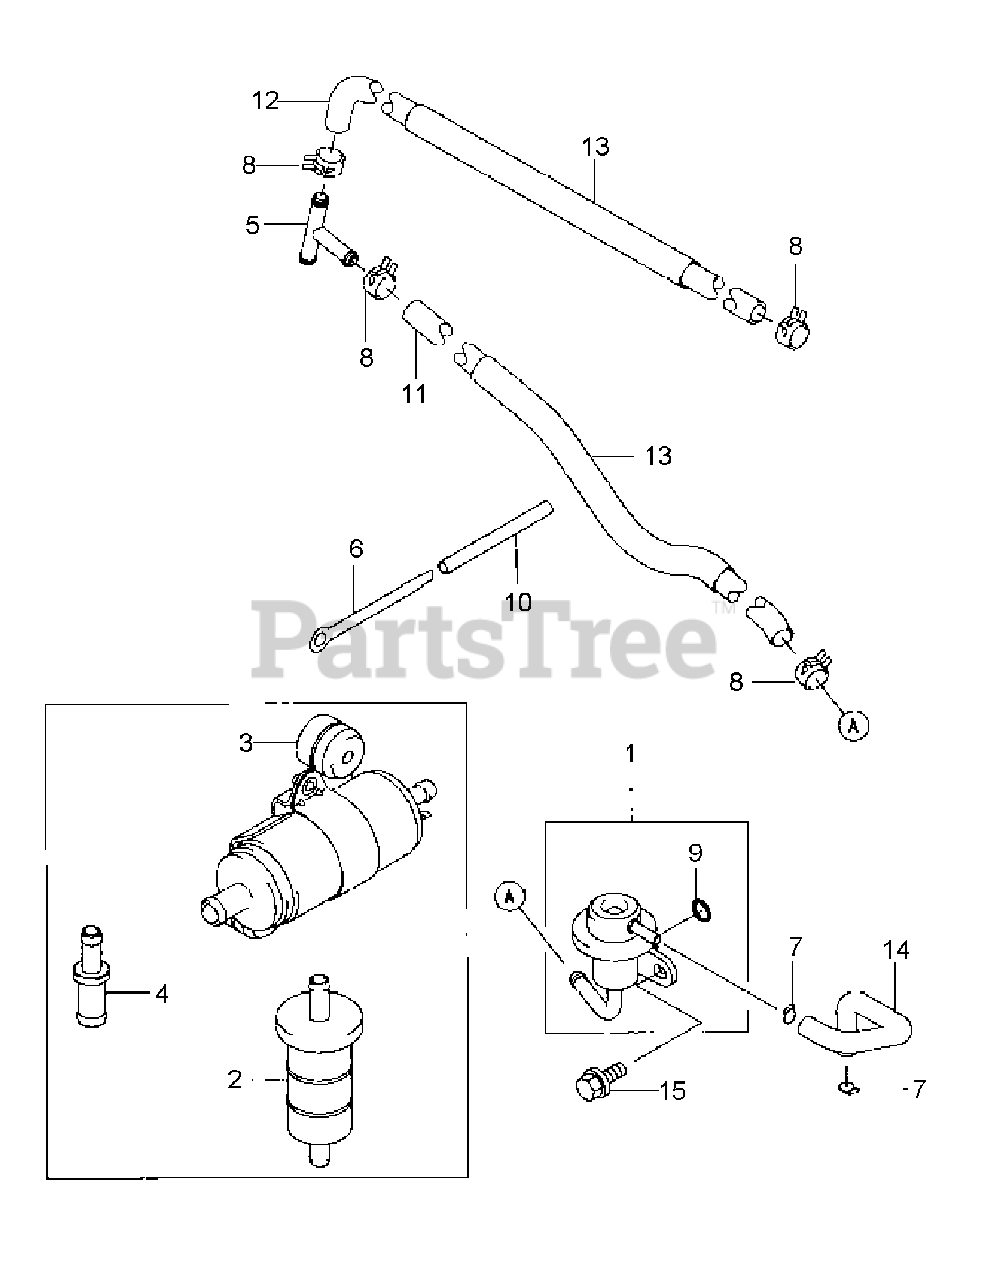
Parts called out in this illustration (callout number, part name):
1	FUEL REGULATOR
2	FUEL FILTER
8	CLAMP
9	O-RING FUEL REGULATOR
15	FLANGED BOLT
